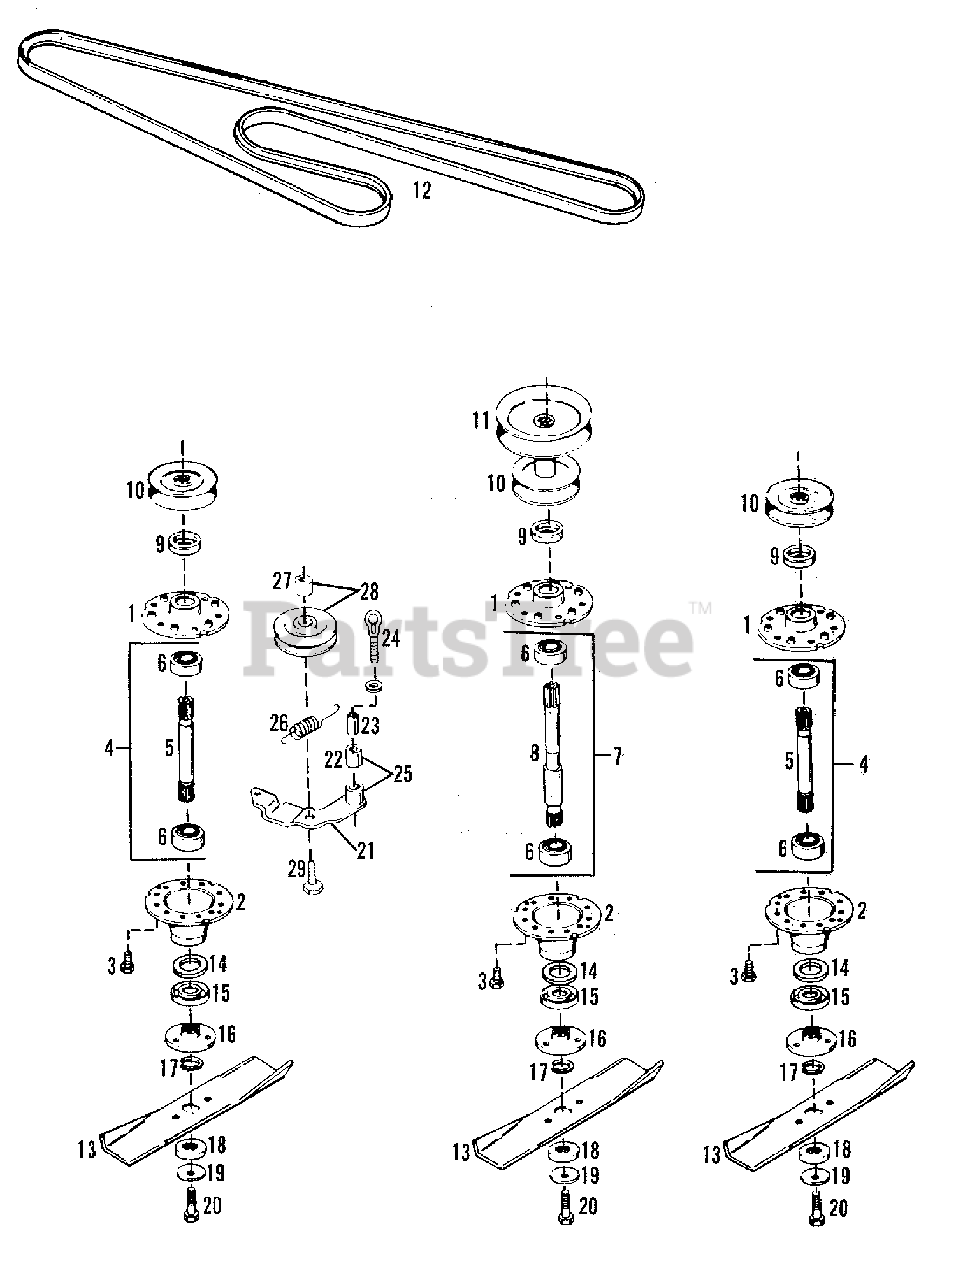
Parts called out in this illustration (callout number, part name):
1	HOUSING, Top
2	HOUSING, Bottom
3	SCREW, Taptite, 5/16NC x 3/4
4	BEARING ASSEMBLY, Shaft
5	SHAFT, Arbor
7	BEARING ASSEMBLY, Center Shaft
8	SHAFT, Arbor, Center
9	SHIELD, Bearing Upper, Arbor
10	PULLEY ASSEMBLY, Deck Drive
10	CAPSCREW, 7/16NC x 1-1/4
10	WASHER, Plain, 29/64 x 1-1/4 x 1/4
10	LOCKWASHER, 7/16
11	PULLEY ASSEMBLY, Center Shaft
11	CAPSCREW, 7/16NC x 1-1/4
11	WASHER, Plain, 29/64 x 1-1/4 x 1/4
11	LOCKWASHER, 7/16
12	V-BELT, Arbor Drive
13	BLADE, 48" Mower
14	WASHER, Shim
15	SHIELD, Grass
16	ADAPTER, Blade
17	COLLAR, Mower Arbor
18	WASHER, Spline
19	WASHER, Spring
20	CAPSCREW, 7/16NC x 1, Gr.8
21	LEVER ASSEMBLY, Idler
23	RACE, Inner
24	WASHER, Plain, 3/8 x 7/8 x 14 Ga.
24	LOCKWASHER, 3/8
25	LEVER ASSEMBLY, Idler
28	PULLEY ASSEMBLY
29	CAPSCREW, 3/8NC x 1-1/4
29	WASHER, Plain, 3/8 x 7/8 x 14 Ga.
29	LOCKWASHER, 3/8
29	NUT, Lock, 3/8NC
